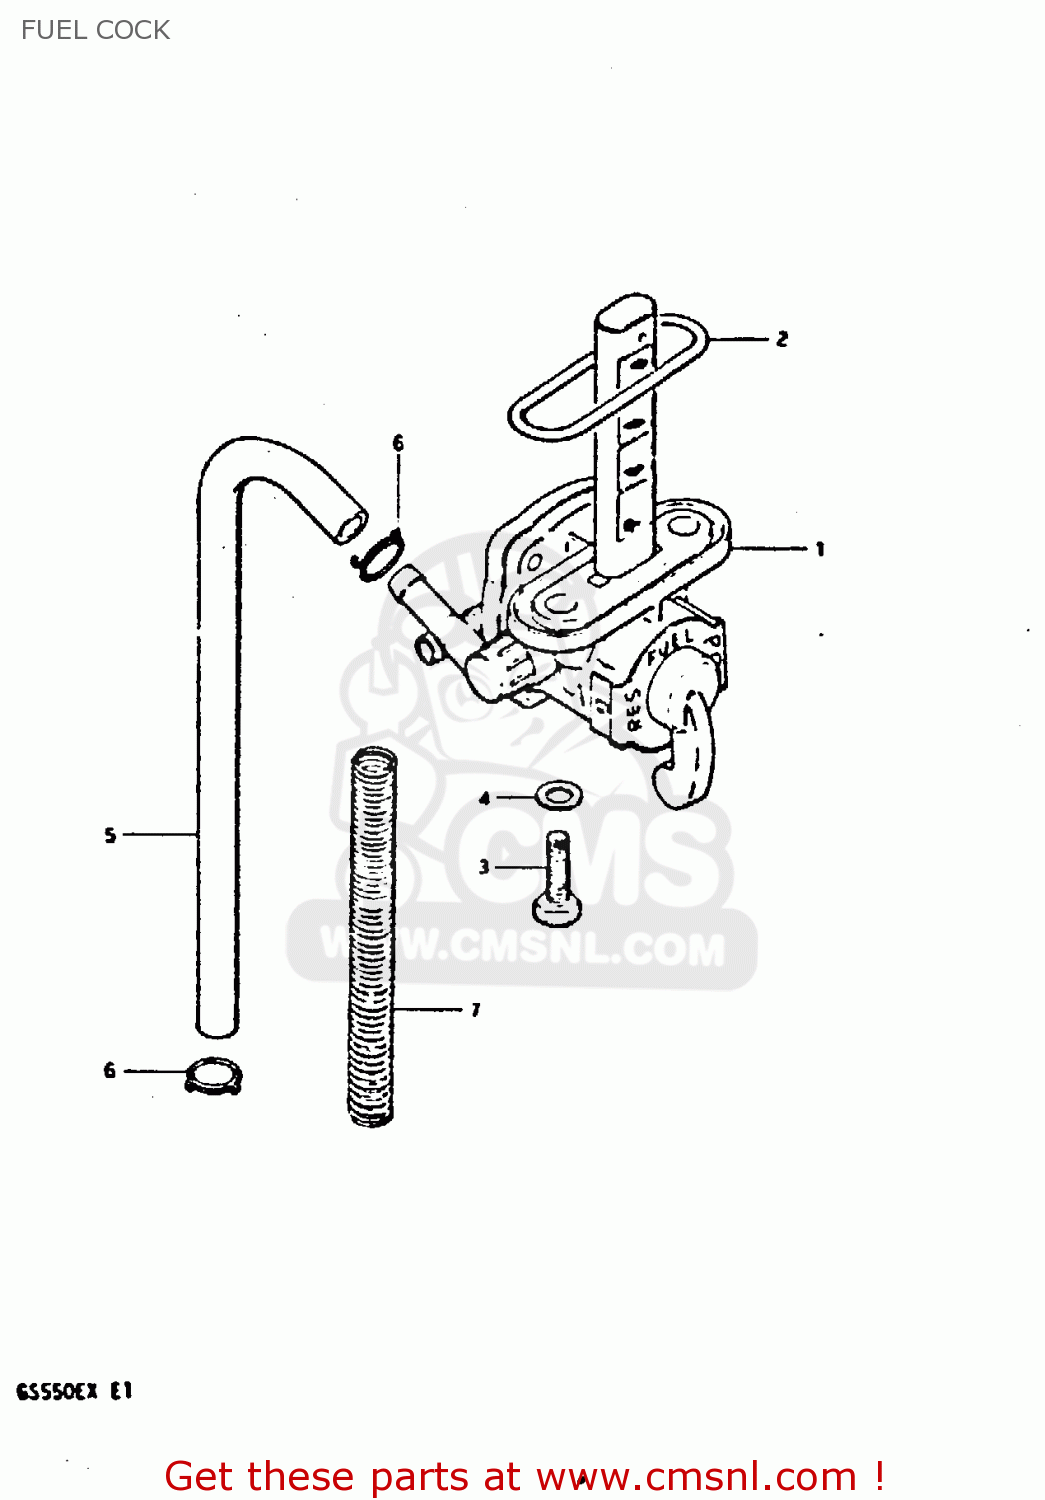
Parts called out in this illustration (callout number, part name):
1	COCK ASSEMBLY,FUEL
2	O RING
3	SCREW(6X14)
4	GASKET
5	HOSE
6	CLIP
7	SPRING
